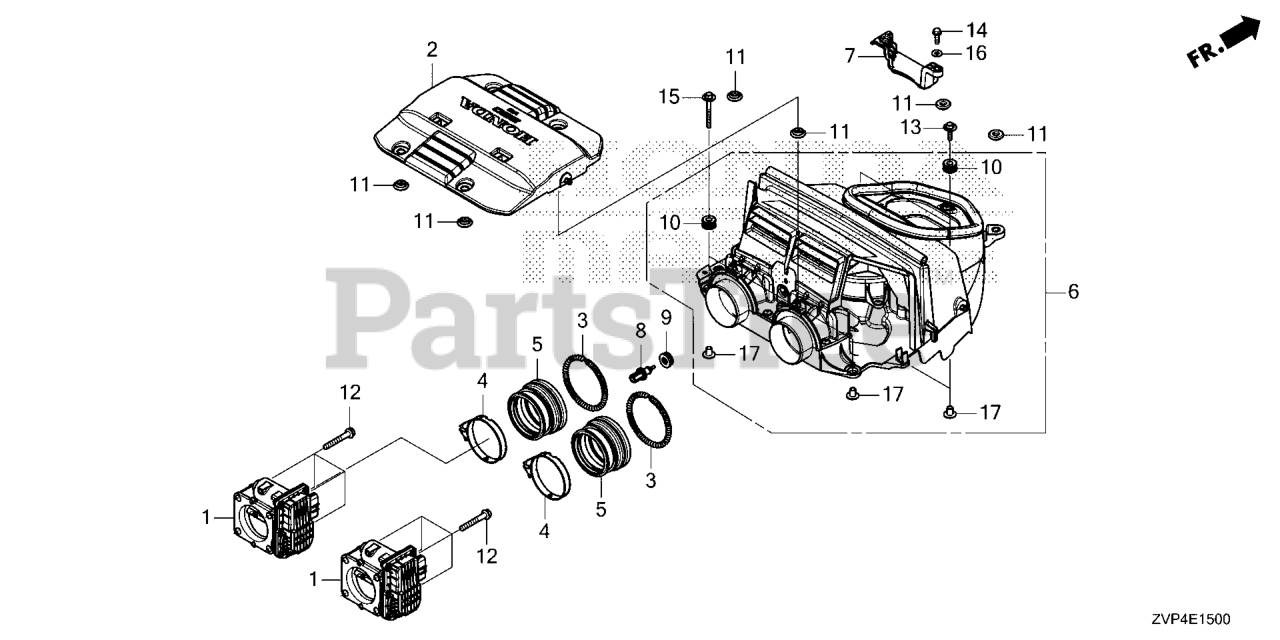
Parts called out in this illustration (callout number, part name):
1	ELECTRONIC CONTL
2	GUARD, THROTTLE BODY
3	SPRING, AIR FLOW TUBE
4	BAND, AIR FLOW
5	GROMMET, MUFFLER
6	COVER, COOLING FAN
7	GUARD COMP
8	SENSOR ASSY., AIR TEMPERATURE
9	GROMMET, TA SENSOR
10	GROMMET, CASE (LOWER)
11	GROMMET, SIDE COVER
12	BOLT, FLANGE (8X55)
13	BOLT-WASHER (6X25)
14	BOLT (6X20)
15	BOLT-WASHER (6X60)
16	WASHER, PLAIN (6MM)
17	COLLAR (12X6.5)
